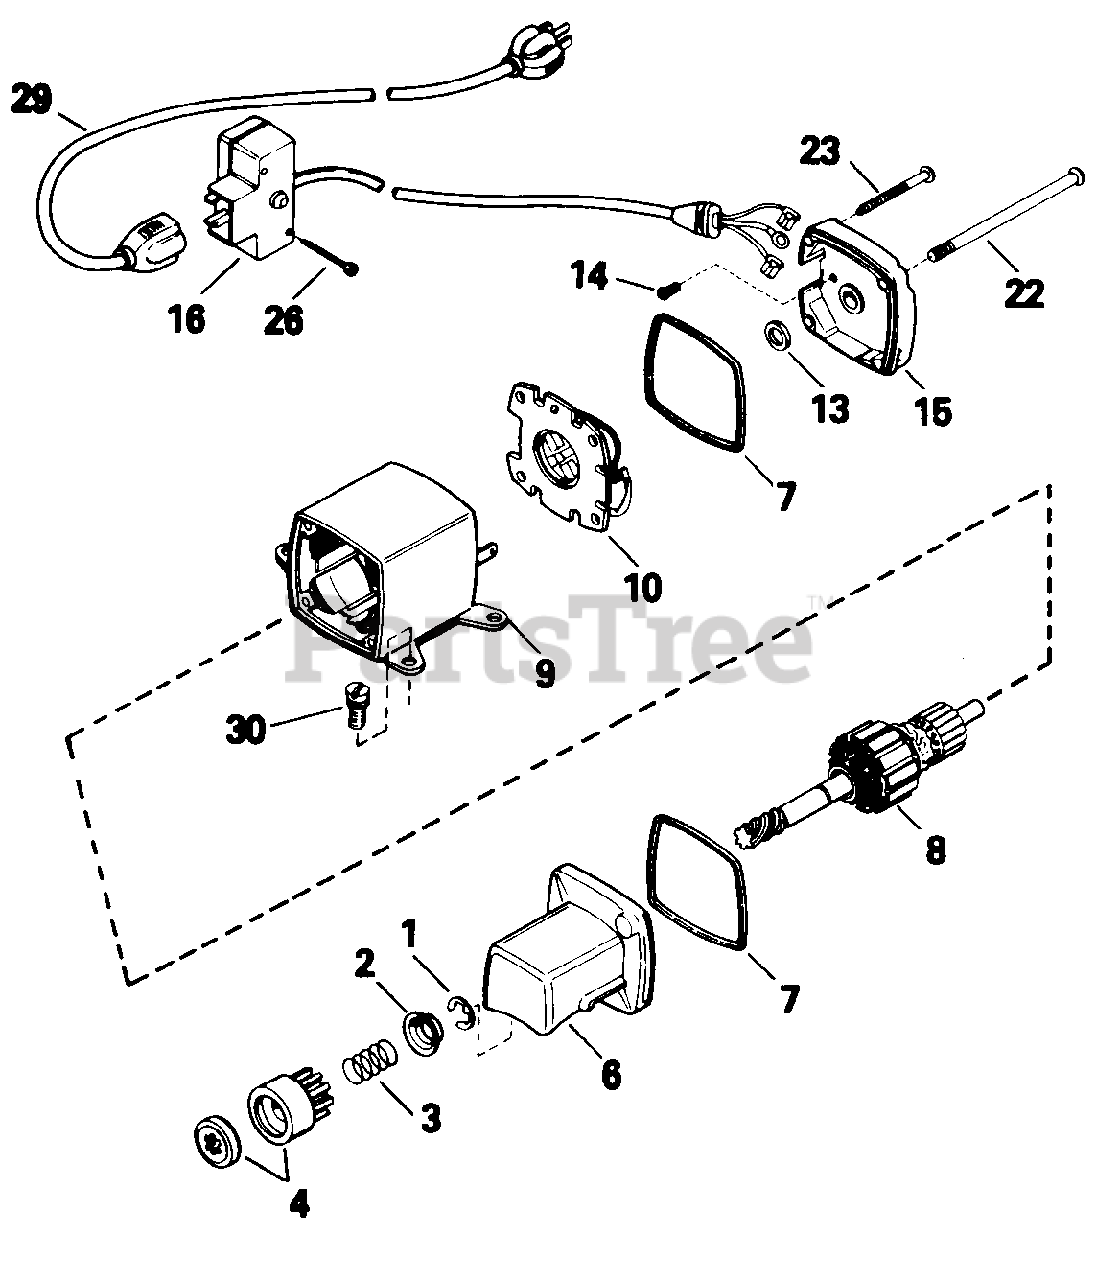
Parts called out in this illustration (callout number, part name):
1	Ring, Retainer
2	Retainer, Spring
3	Spring, Anti-Drift
4	Nut & Gear
6	Cap Ass'y., Drive End
8	Armature
9	Housing Ass'y.
10	Card Ass'y., Brush
13	Washer, Thrust
14	Screw, Ground
15	Cap Ass'y., Commutator End
16	Box Ass'y., Switch
22	Bolt, Case
23	Screw, Grounding
26	Screw, Hex Hd. Self-Tap, 6-32 x 21/2
29	Cord, Extension (10'6")
30	Screw, Hex Hd. Self-Tap, 1/4-20 x 11/16
